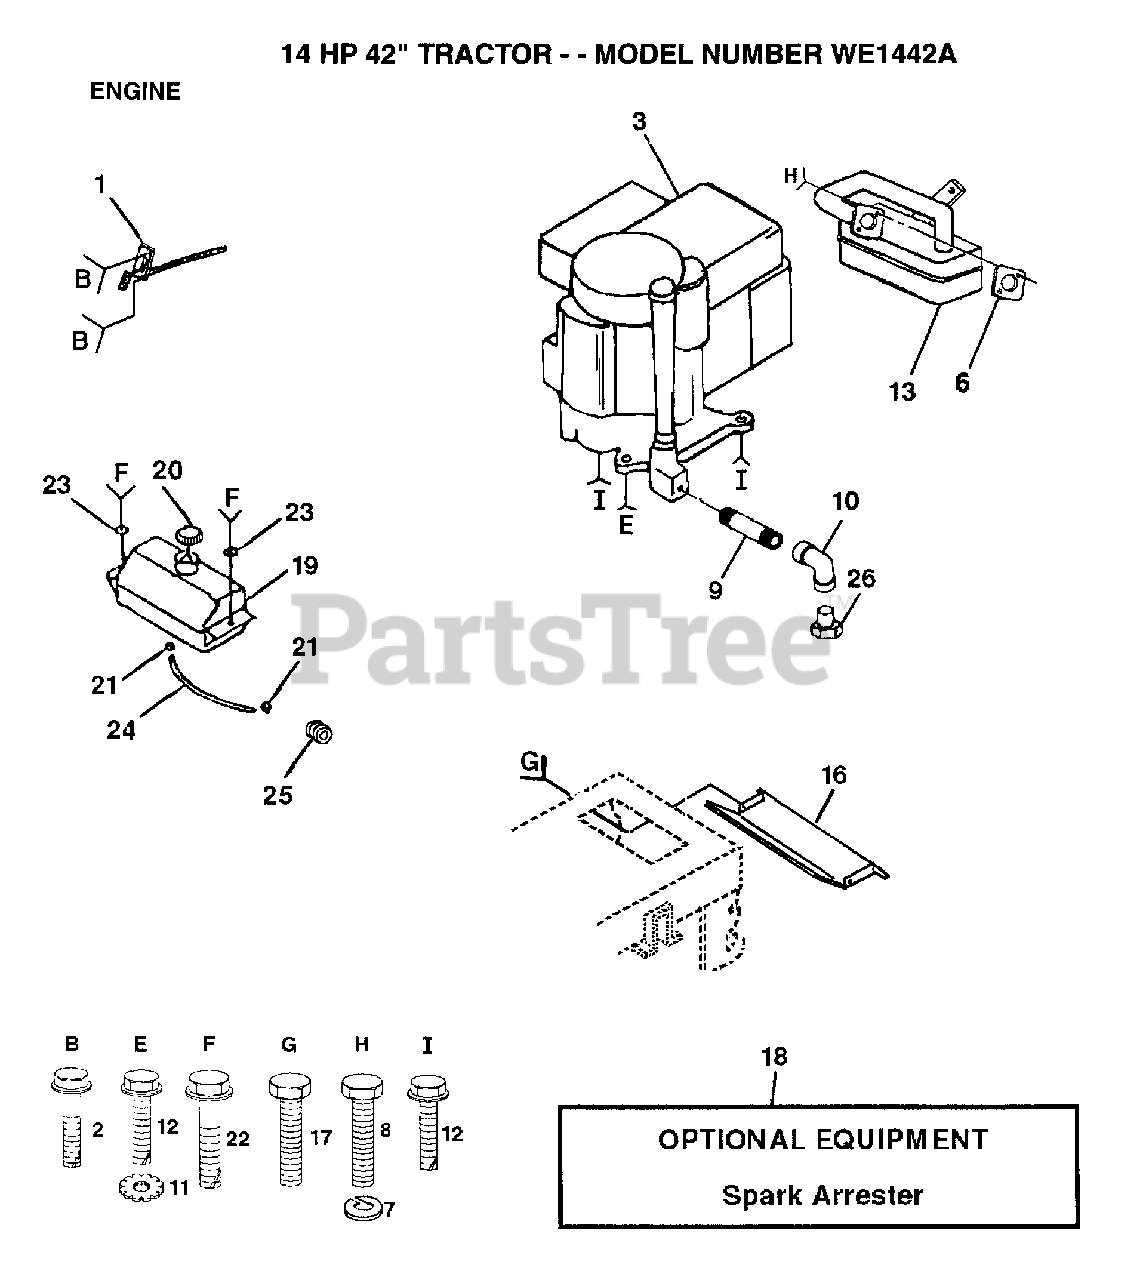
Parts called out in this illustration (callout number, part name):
1	THROTTLE CONTROL
2	SCREW LT
7	LOCKWASHER
8	SCREW
9	PIPE NIPPLE
10	ELBOW
11	LOCKWASHER
12	SCREW
13	MUFFLER
16	HEAT SHIELD
17	SCREW
19	TANK.FUEL.LT.
21	HOSE CLAMP
22	SCREW HEX CRT
23	WASHER
24	FUEL LINE T
